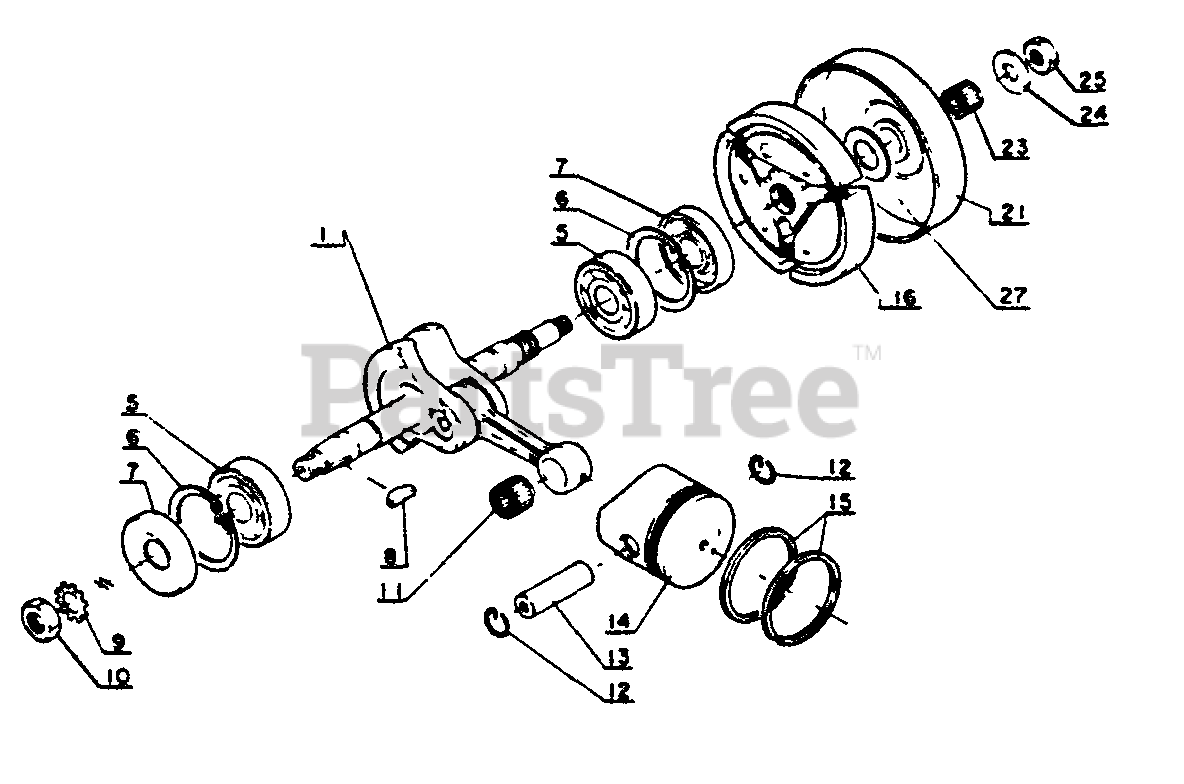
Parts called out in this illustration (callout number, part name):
1	CRANKSHAFT
5	BEARING, BALL - 6201 C3
6	RING, SNAP Ø32
7	SEAL, OIL
11	BEARING, NEEDLE
12	RING, RETAINING
13	PIN, PISTON
15	RING, PISTON
16	CLUTCH ASSY
16	SPRING, CLUTCH
16	SHOE, CLUTCH
16	HUB, CLUTCH
16	PLATE, CLUTCH
16	RIVET
21	CASE, CLUTCH
23	BEARING, NEEDLE 8
24	WASHER, CLUTCH
25	LOCKNUT - 6
27	WASHER, CLUTCH
